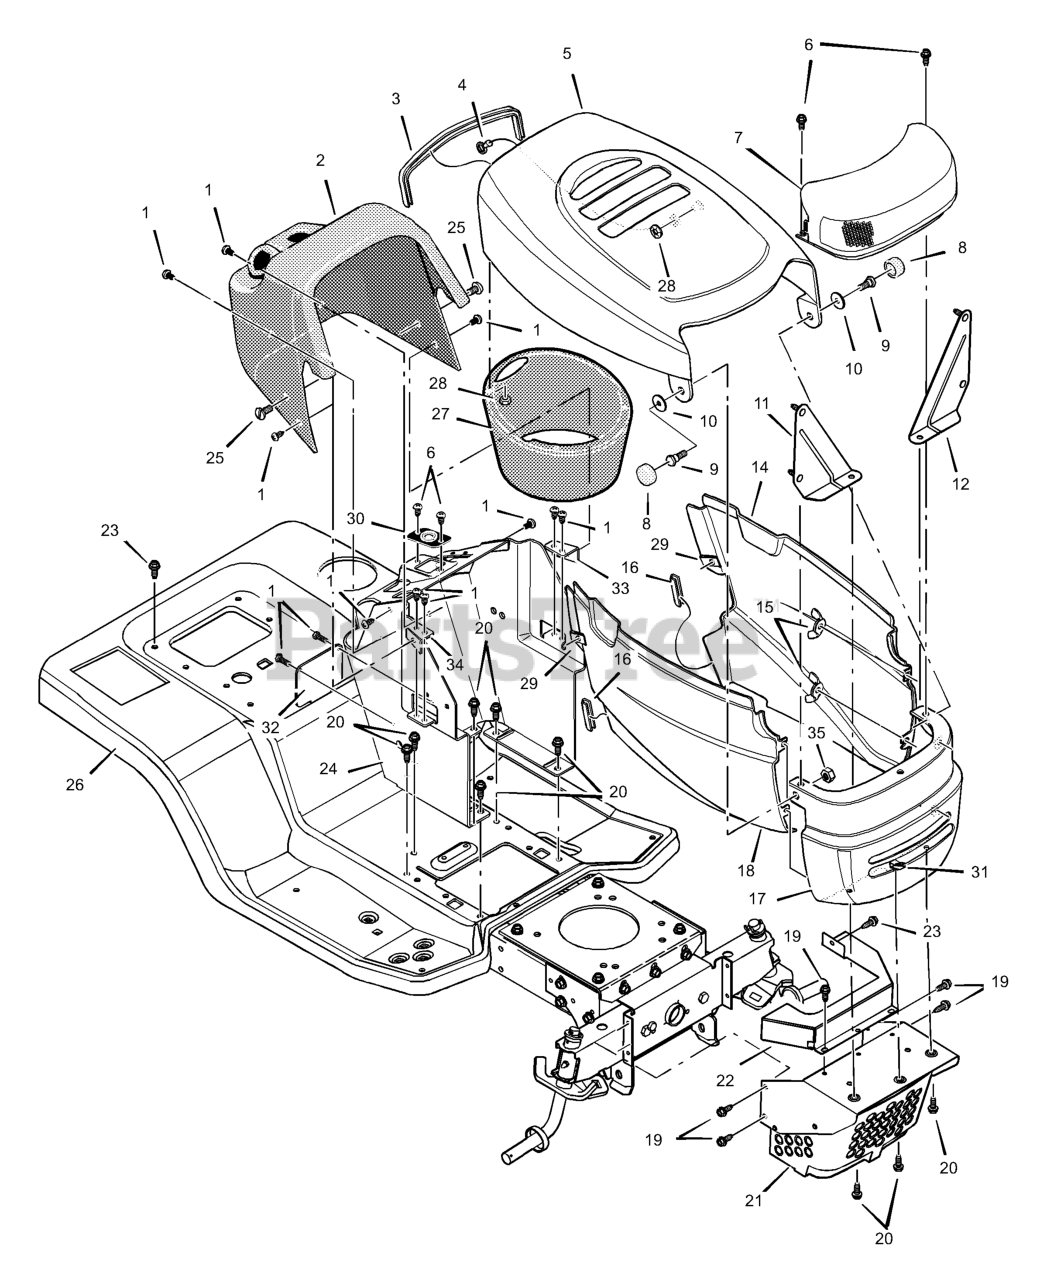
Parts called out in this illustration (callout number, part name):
1	Screw
3	Trim 2.23"
5	Hood Assembly
7	Lens & Reflector Assembly
8	Cap, Pivot
9	Bolt, Shoulder
10	Base, Pivot
11	Brace, Right Grille Assembly
12	Brace, Left Grille Assembly
14	Panel, Left Side
15	Wingnut
16	Trim 0.39"
18	Panel, Right Side
21	Guard Assembly, Muffler
22	Shield, Upper Heat
24	Console
26	Deck Seat
28	Retainer, Push
29	Cap, Push
30	Bearing, Steering
32	Panel, Access
33	Bracket, Right Console
34	Bracket, Left Console
35	Nut
